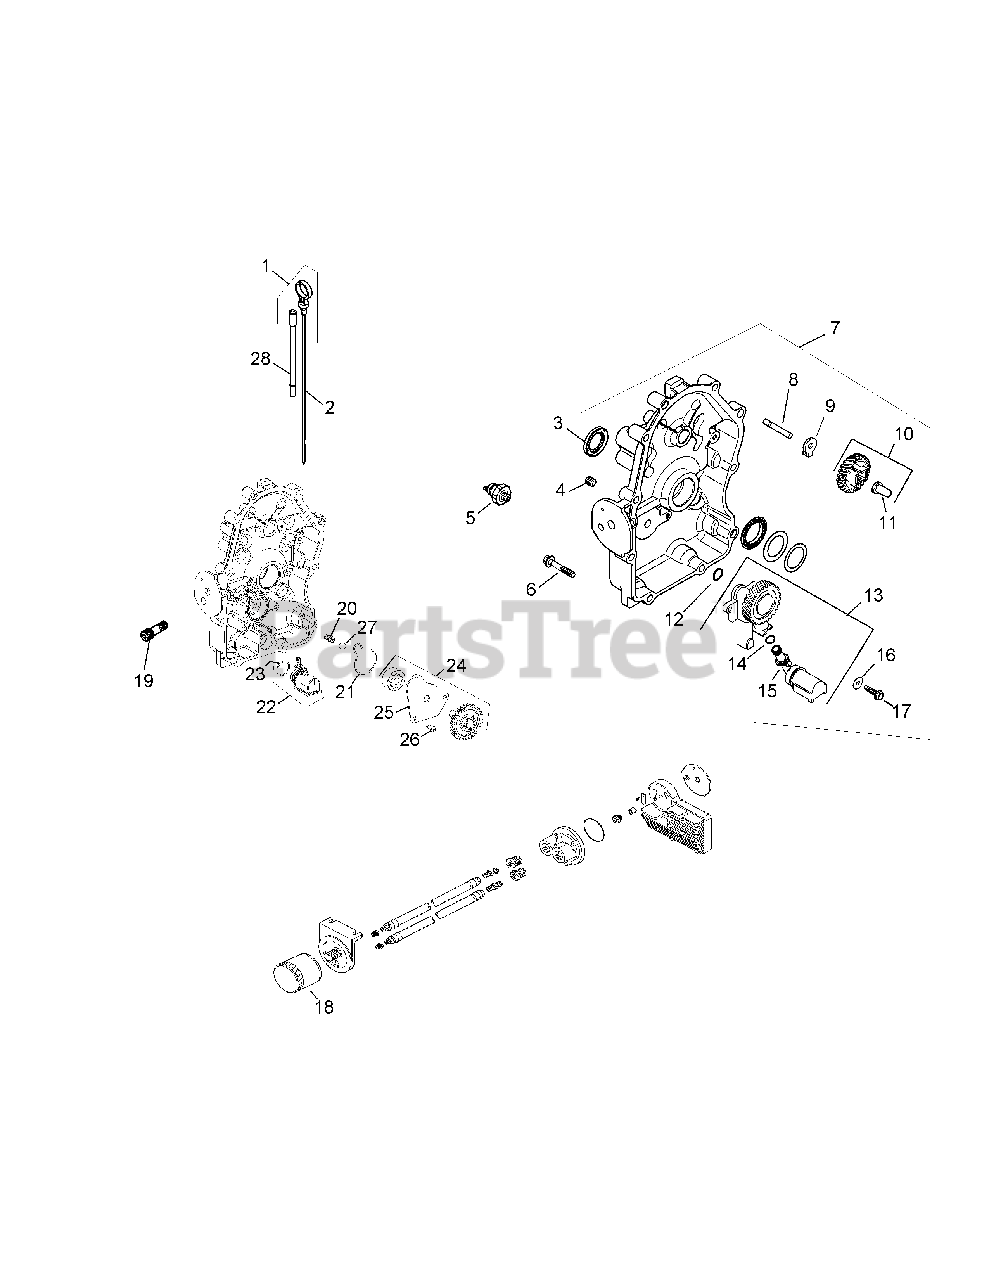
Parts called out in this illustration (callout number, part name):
1	Dipstick/Dipstick Tubes Kit
4	Countersink Pipe Plug, 1/8
5	Oil Pressure Switch
6	Flange Screw, M8 x 1.25 x 45
7	Closure Plate Assembly
8	Governor Gear Shaft
10	Governor Gear Kit w/ Pin
11	Governor Regulating Pin
13	Oil Pump Assembly Kit
14	Oil Pick-Up O-Ring
16	Flat Washer, 1/4 x 5/8
17	Thread Forming Screw
19	Oil Filter Nipple
20	Compression Spring
21	Oil Pump Cover Seal
22	Oil Pick-Up Assembly
23	Oil Pick-Up O-Ring
24	Oil Pump Assembly
25	Oil Pump Cover
26	Button Head Screw
27	Pressure Relief Ball
28	Dipstick Tube
